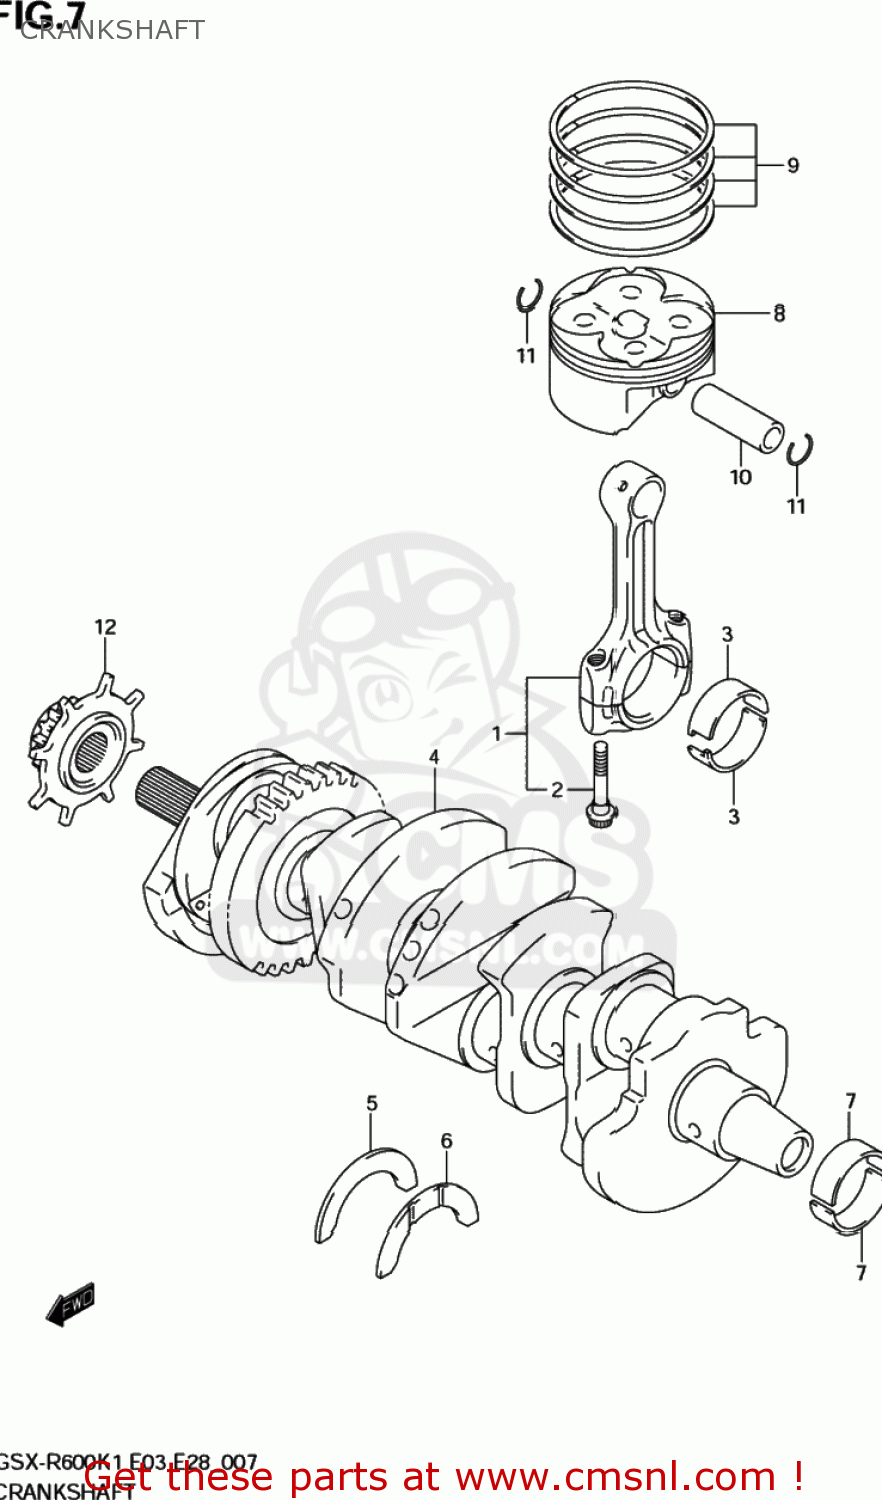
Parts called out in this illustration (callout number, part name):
1	CONNECTING ROD ASSY
2	BOLT,CONNECTING ROD
2A	PIN,CONNECTING ROD
3	BEARING,CRANK PIN
4	CRANKSHAFT SET
5	BEARING,CRANK THRUST(GREEN)
6	BEARING,CRANK THRUST(RED)
7	BEARING,CRANKSHAFT
8	PISTON
9	RING SET,PISTON
10	PIN,PISTON
11	RING,SNAP 14MM
12	SPROCKET,CAM CHAIN DRIVE
